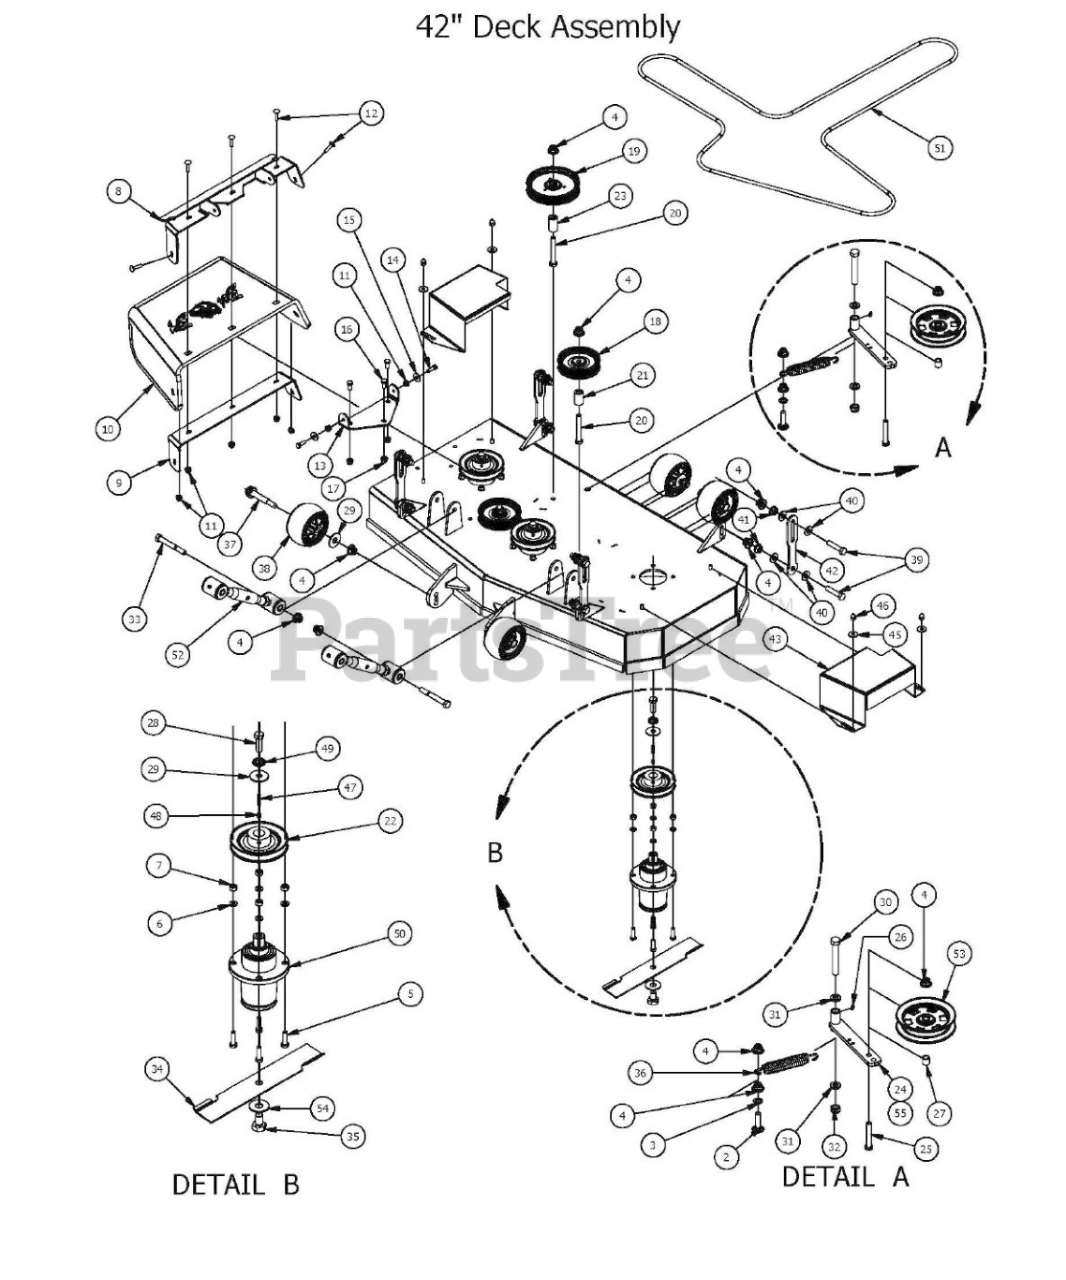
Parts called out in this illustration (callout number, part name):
1	42" Compact Outlaw Deck-Welded Shell
2	1/2 x 2" Carriage Bolt
3	517 Square Hole Round Washer
4	1/2-13 Nylon Flange Nut
5	3/8" x 1 1/4" Hex Bolt
6	3/8" Lock Washer
7	3/8" Hex Nut
8	Discharge Upper Chute Bracket
9	Discharge Lower Chute Bracket
10	Rubber Discharge Chute
11	5/16" Nylon Flange Nut
12	5/16" x 1 1/4" Carriage Bolt
13	Discharge Chute Hanger (Deck Mounted)
14	5/16" x 1" Bolt
15	.360 ID Plastic Washer
16	3/8" x 3/4" Hex Bolt
17	3/8" Flange Nut
18	4 3/4" Idler Pulley
19	5-3/4 Idler Pulley-Capitol Stampings
20	1/2 x 3 1/2 Flange Bolt Grade 8
21	Idler Pulley Standoff
22	5" Spindle Deck Pulley
23	1 3/4" Pulley Spacer
24	Deck Idler
25	1/2-13 x GR 5 Hex Bolt Zinc
26	1/4" Press in Grease Fitting
27	Spacer 3/4 OD x 1/2 ID x 314 Length
28	1/2"-20 x 1 1/2 - Grade 5 Fine Thread Bolt
29	1/2" Belleville Washer
30	5/8" x 4" Hex Bolt
31	.630 ID X 1.122 OD X.142 THK Flat Washer Nylon
32	5/8" Nylock (1/2 Jam)
33	1/2" x 4" Bolt (Grade 8)
34	42" High Lift Blade
35	5/8" x 1 1/2" Grade 8 Hex Bolt (Fine)
36	2015 Deck Idler Spring
37	Deck Wheel Bolt
38	Anti-Scalp Roller
39	1/2-13X 2-1/4 GR Hex Bolts
40	505 Nylon Spacer
41	1/2" Flange Nut
42	Deck Hanging Tab longer
43	Pulley Cover Compact Outlaw-Left
44	Pulley Cover Compact Outlaw-Right
45	.360 ID Plastic Washer-Black
46	Acorn nut-pulley Cover
47	1/4" x 1" Key
48	5/16 Set Screw
49	1/2" Lock Washer Zinc
50	Spindle Assembly
51	B 138 Deck Belt
52	Turnbuckle
53	5" Idler Pully
54	5/8" Flat Washer
55	Deck Idler Assembly (Parts 4,24,25,26,27,53)
